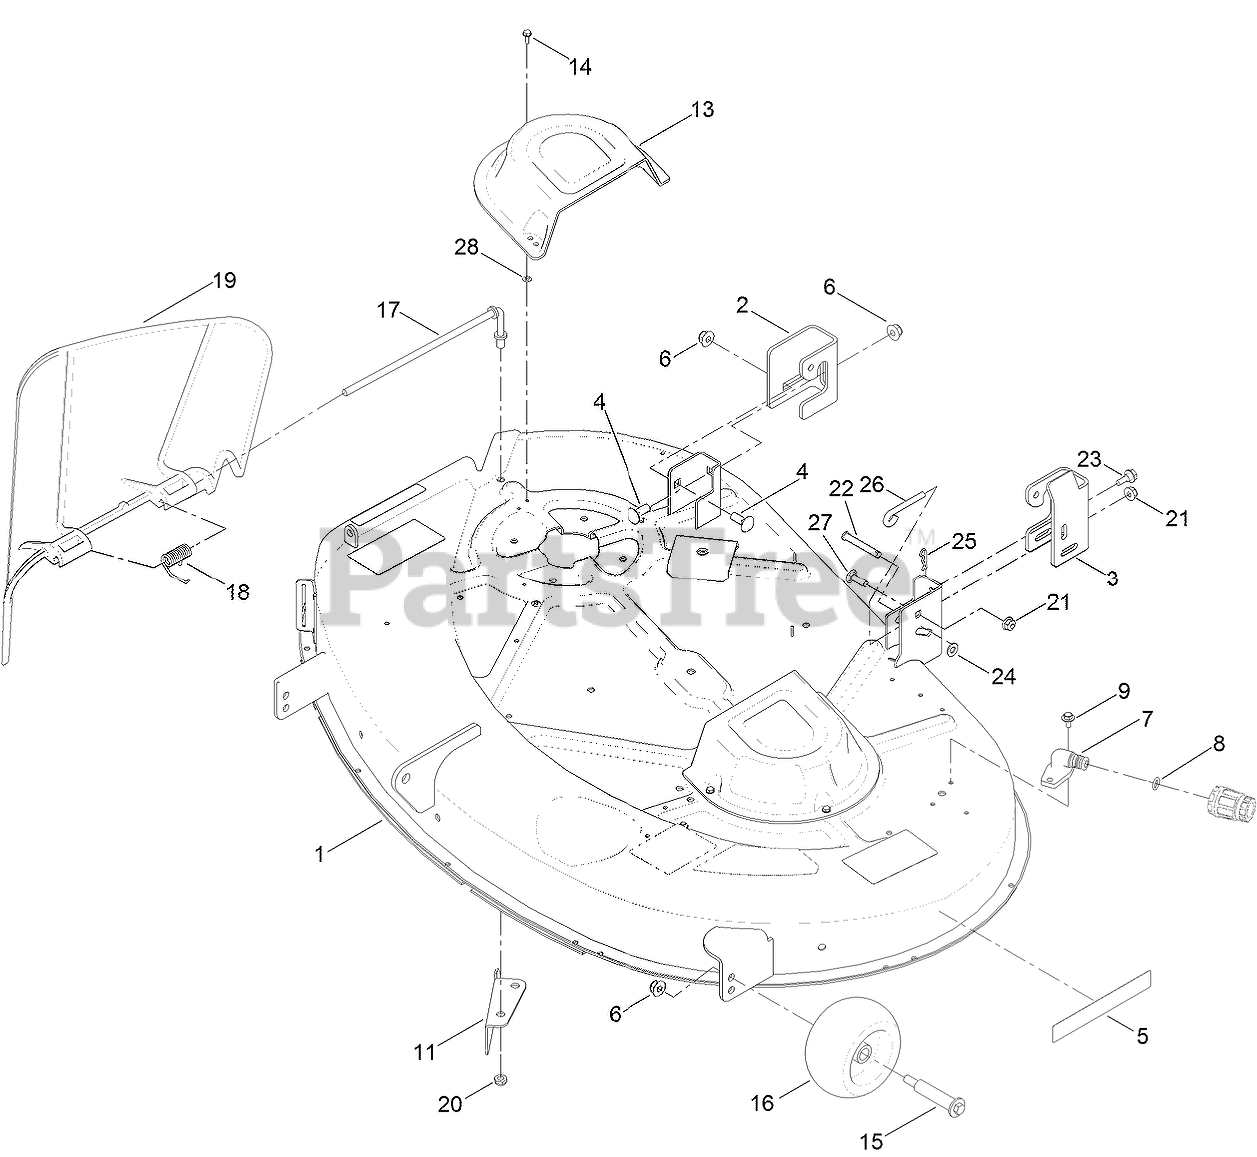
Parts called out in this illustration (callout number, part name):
1	42 INCH DECK AND DECAL ASM
2	BRACKET-HANGER, RH
3	BRACKET-HANGER, LH
4	BOLT-CARR
5	DECAL-RECYCLER
6	NUT-HF, NI
7	FITTING-WASHOUT
8	O-RING
9	SCREW-HHFTF
11	BAFFLE-CUTOFF
13	COVER-BELT
14	SCREW-TAPTITE
15	BOLT-SHOULDER
16	ROLLER-SCALP, ANTI
17	ROD-PIVOT
18	SPRING-TORSION
19	DEFLECTOR
20	NUT-LOCK, NI
21	NUT-HF, NI
22	PIN-CLEVIS
23	SCREW-SHOULDER, HHF
24	WASHER-PLAIN
25	PIN-COTTER
26	ROD-LEVEL, DECK
27	SCREW-CARR
28	NUT-RETAINING
